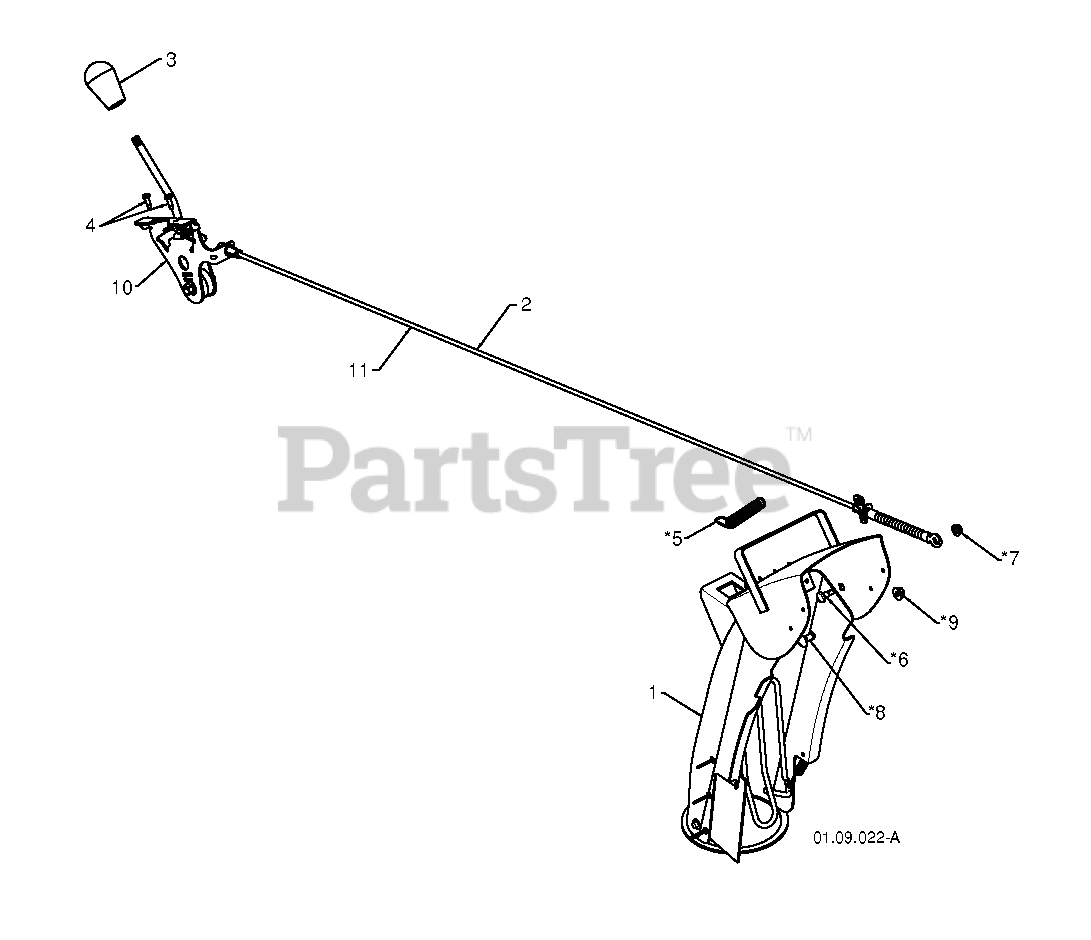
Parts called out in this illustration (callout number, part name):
2	CONTROL.ASM.DEFLECTOR
3	KNOB LEVER, BLACK
4	SCREW #10-24 X 5/8
6	BOLT, SHOULDER
7	NUT.HEX.FLANGE.1/4
8	BOLT
9	NUT, LOCK 5/16-18
10	CHUTE.DEFLECTOR.HEAD.SERVICE.
11	SERVICE.CHUTE.DEF.CBL.BLK
